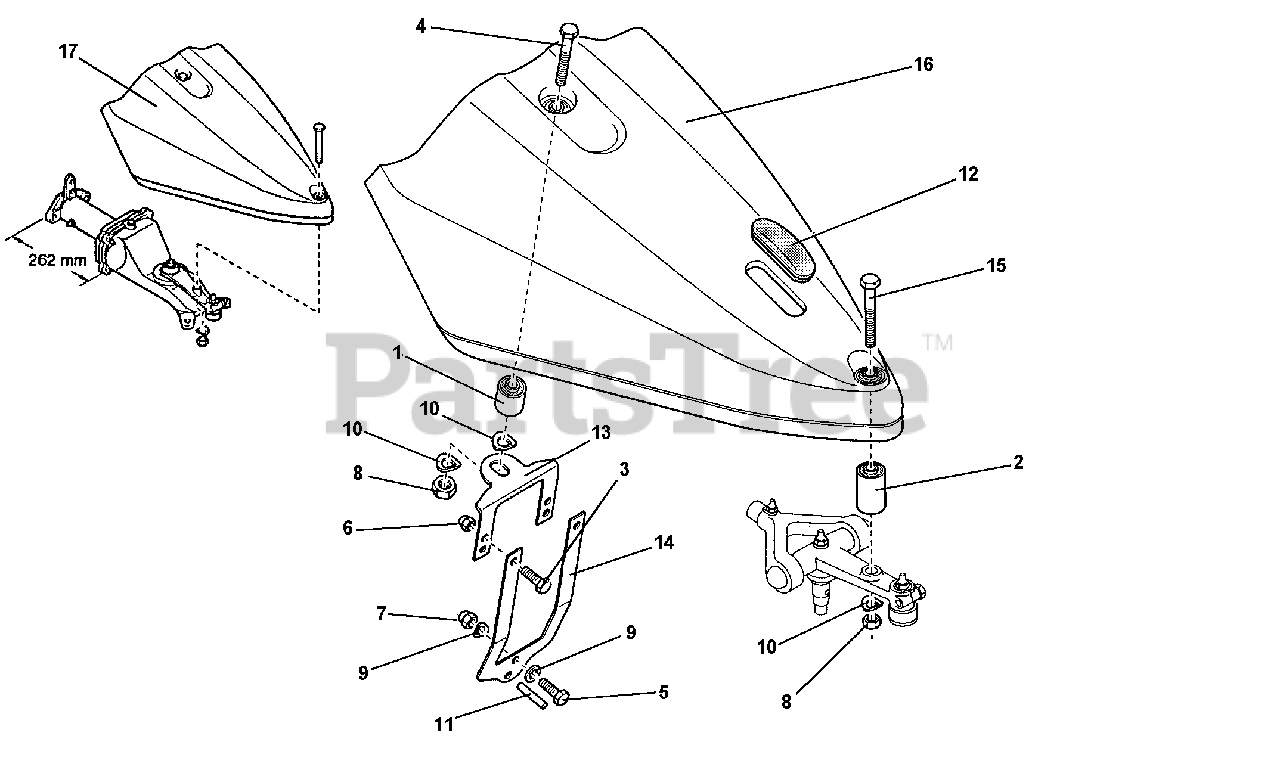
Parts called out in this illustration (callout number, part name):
1	SILENTBLOCK
2	SILENTBLOCK
3	SCREW, M6 X 14
4	SCREW, M14 X 50
5	SCREW, M8 X 30
6	NUT, SELF LOCKING M6
7	NUT, SELF LOCKING M8
8	NUT, SELF LOCKING M14
9	WASHER, LOCK M8.4
10	WASHER, LOCK M15
11	PIN, LOCKING M8 X 20
12	OVAL PLUG FOR PROTECTION
13	UPPER COUPLING
14	LOWER COUPLING
15	SCREW M14 X 90
17	GUARD FOR OIL BATH
